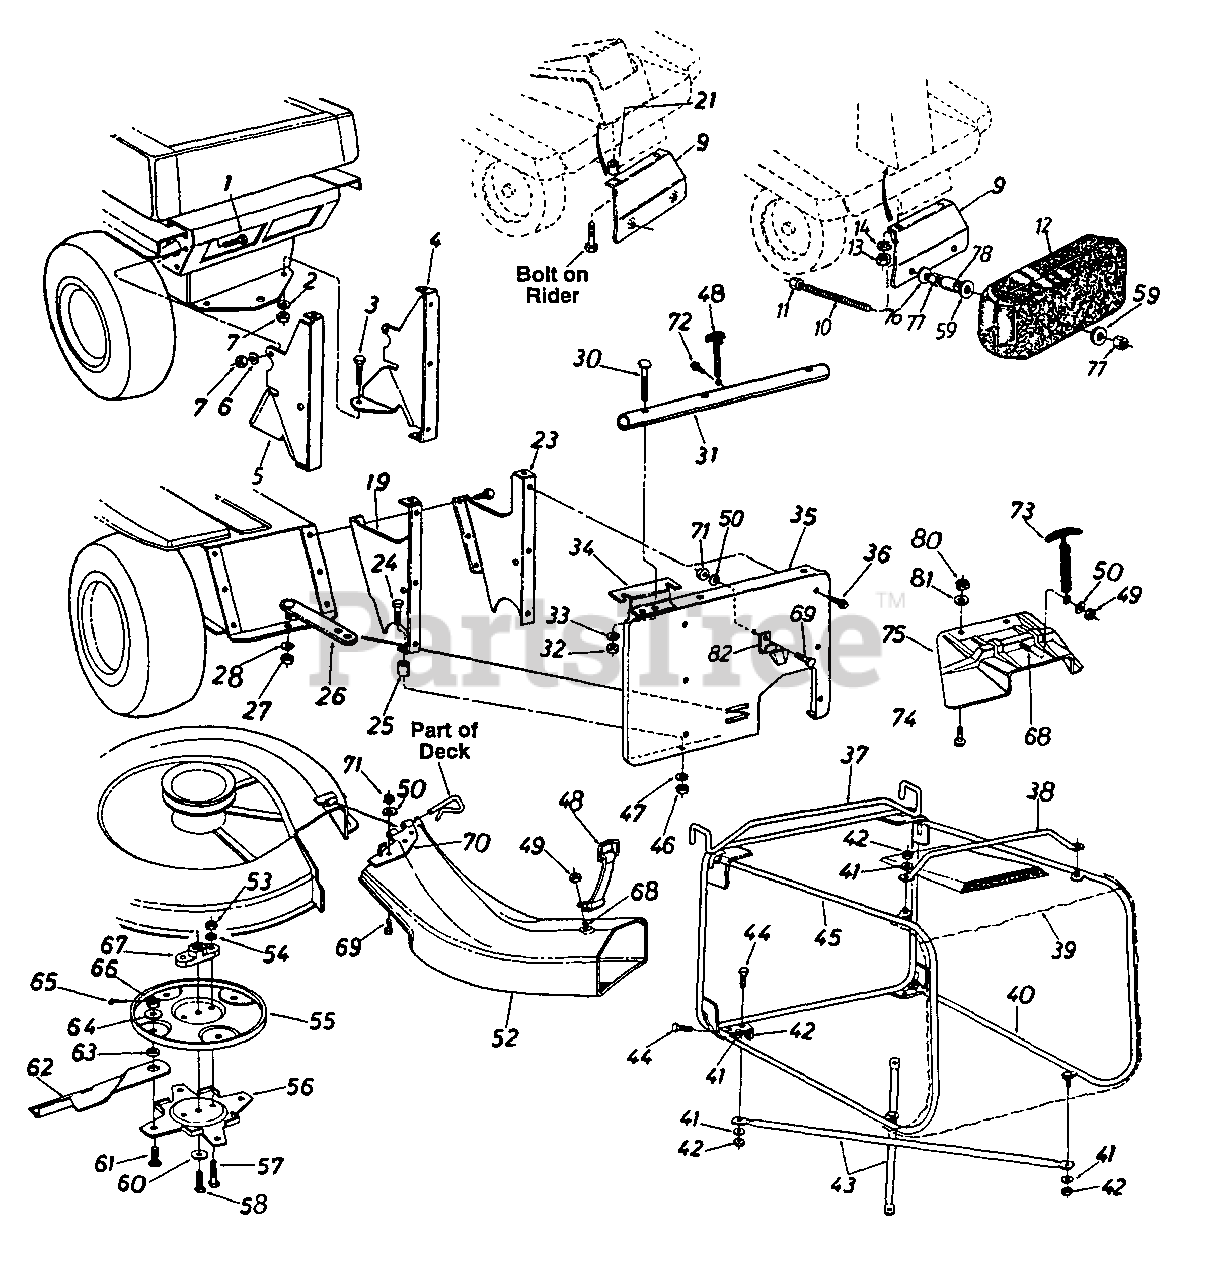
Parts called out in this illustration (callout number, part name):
1	Hex Bolt 5/16-18 x 1" Lg.
2	L-Wash. 5/16" I.D.
4	Catcher Support Brkt. - R.H.
5	Catcher Support Brkt. - L.H.
7	Hex Nut 5/16-18 Thd.
11	Hex Nut 7/16-14 Thd.
12	Counterweight 38 lbs.
19	Catcher Support Brkt. - L.H.
21	Spacer .380" I.D. x 1" O.D. x .32" Lg.
23	Catcher Support Brkt. - R.H.
24	Hex Bolt 5/16-18 x 1.5" Lg.
25	Spacer .38" I.D. x .47" O.D. x 1" Lg.
28	L-Wash. 1/2" I.D.
30	Curved Carriage Bolt 5/16-18 x 1.75" Lg.
36	Hex Wash. Hd. Self-Tap Scr. 1/4-20 x .5" Lg.
42	Hex L-Nut 1/2-20 Thd.
43	Bottom Cross Brace
44	Hex Bolt 1/4-20 x .62" Lg.
48	Retainer Strap
49	L-Wash. 1/4" I.D.
52	R.D. Banana Chute Ass'y.
53	Hex Nut 5/16-24 Thd.
55	Upper Blade Disc
58	Hex Bolt 3/8-24 x 1.0" Lg.
59	Fl-Wash. .45" I.D.
60	Bell-Wash. .39" I.D. x 1.38"
61	Shld. Bolt .50" Dia. x .36" (Spec.)
62	30" Blade Tip
63	Spacer .505" I.D. x .75" O.D. x 1.25" Lg.
64	Fl-Wash. .5" I.D. x 1.25" O.D.
65	Cotter Pin 3/32" Dia. x 1" Lg.
66	Hex Slotted Nut 1/2-20 Thd.
67	Blade Adapter
68	Hex Bolt 1/4-20 x .5" Lg."
69	Truss Mach. Scr. 1/4-20 x .5" Lg.
72	Hex AB-Tap Scr. 1/4 x .62" Lg.
73	Hook Latch Ass'y.
74	Truss Mach. Scr. 1/4-20 x .50" Lg.
75	R.D. Chute Extension
76	Bell-Wash. 7/16" I.D. x 1.25" O.D.
77	Hex Nut 7/16-14 Thd.
78	Spacer
81	Fl-Wash. .281" I.D. x .5" O.D.
82	Retainer Hook Brkt.
